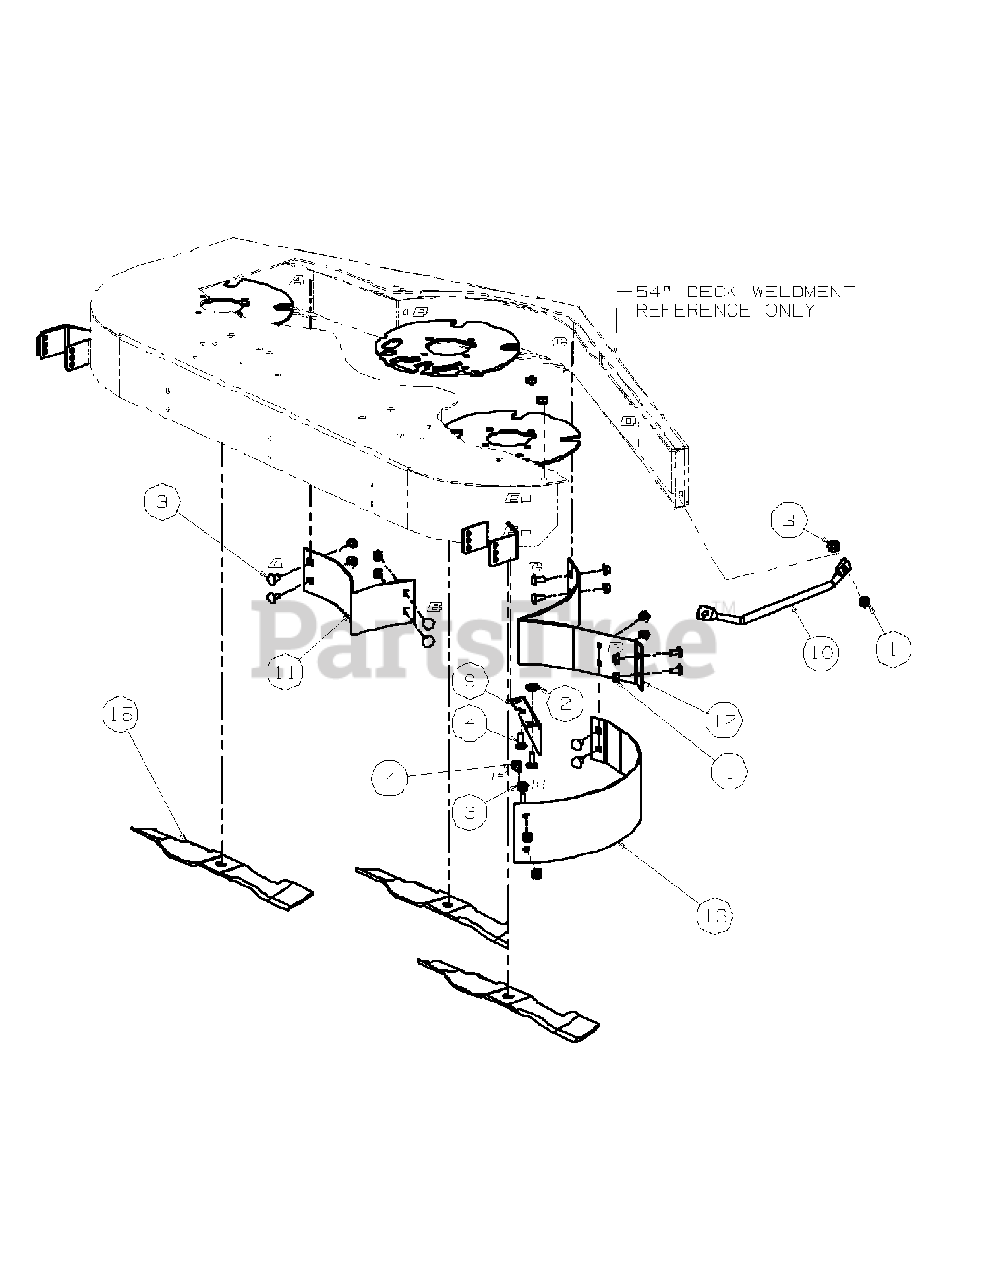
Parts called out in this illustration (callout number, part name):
1	NUT, HEX 3/8-16 FLG LOCK
2	WASHER, IDLER
3	BOLT, CARR 3/8-16 X .75 LG
4	BOLT, CARR 3/8-16 X 1.0 LG
9	BRKT, CHUTE, FAB DECK
10	GUARD, FINGER, FAB DECK
11	Baffle, MULCH, FAB 54 LH
12	Baffle, MULCH, FAB 54 CENTER
13	Baffle, MULCH, FAB 54 RH
15	BLADE, 19.0, MULCH, 0.756 ID
